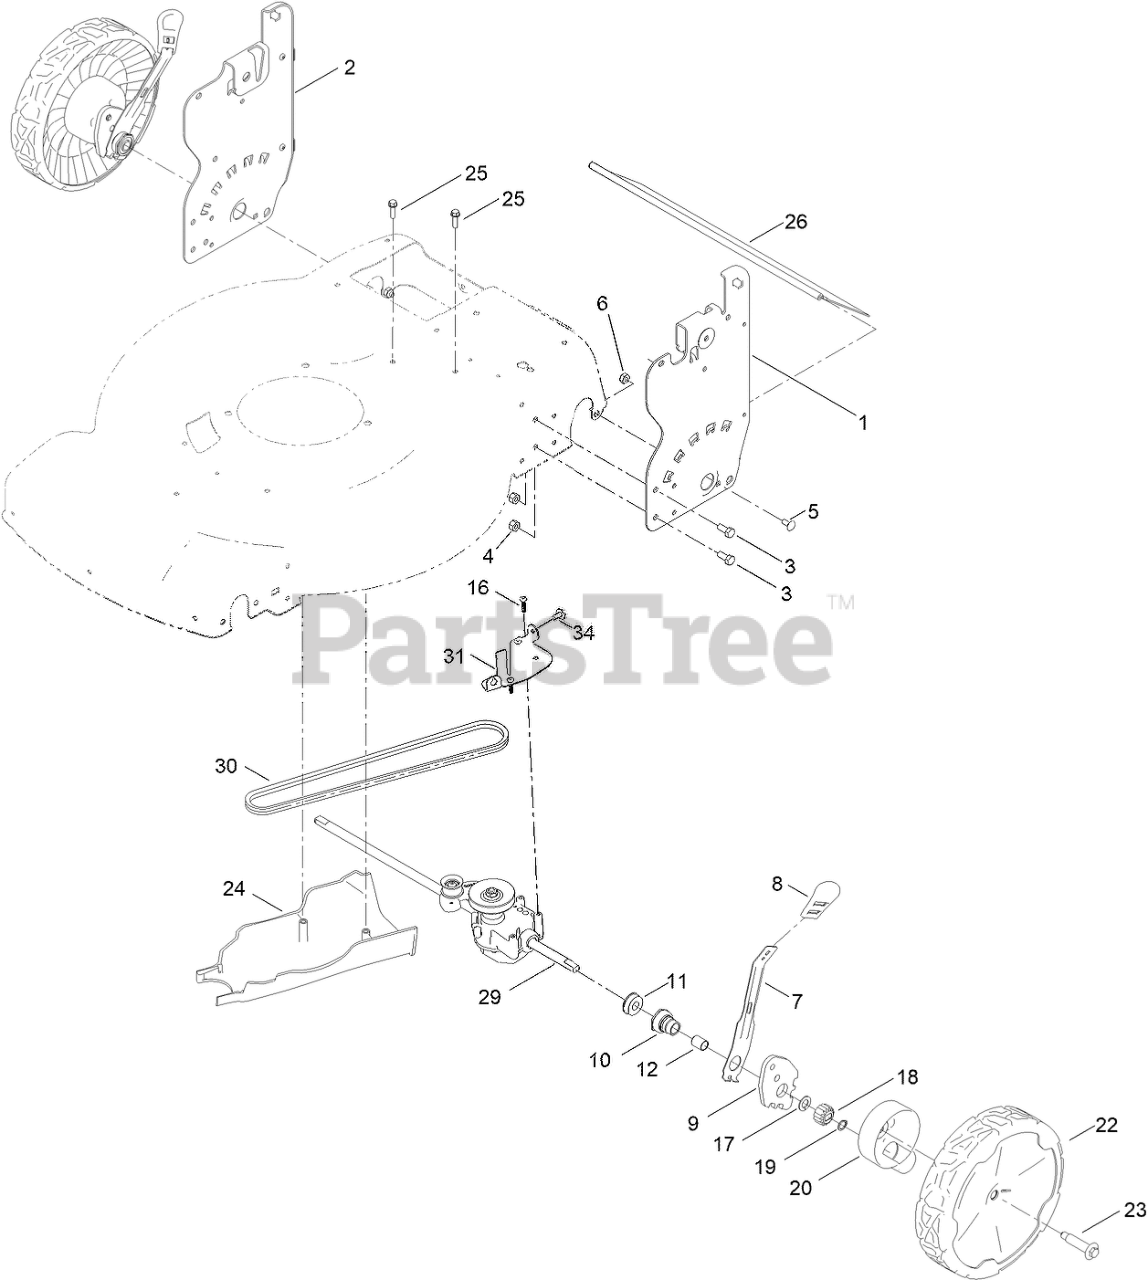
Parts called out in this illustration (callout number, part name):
1	PLATE-HOC, LH (ISO)
2	PLATE-HOC, RH (ISO)
3	SCREW-HH
4	NUT-LOCK, NI
5	SCREW-CARR
6	NUT-LOCK, NI
7	ARM-SPRING
8	KNOB-HOC
9	ARM-PIVOT, REAR
10	RETAINER-BUSHING, HOC
11	BEARING-BALL
12	BUSHING-SLEEVE
16	SCREW-PLASTITE
17	WASHER-THRUST
18	GEAR-PINION, 15T
19	RING-RETAINING
20	ASM-COVER, GEAR (DK GRAY)
22	ASM-9.65" WHEEL, GEARED
23	WHEEL BOLT
24	COVER-BELT, REAR
25	SCREW-HWH
26	SHIELD-TRAILING
29	TRANSMISSION-AWD
30	BELT-AWD, 34.50
31	GUIDE-BELT, AWD
34	SCREW-HHFTF
